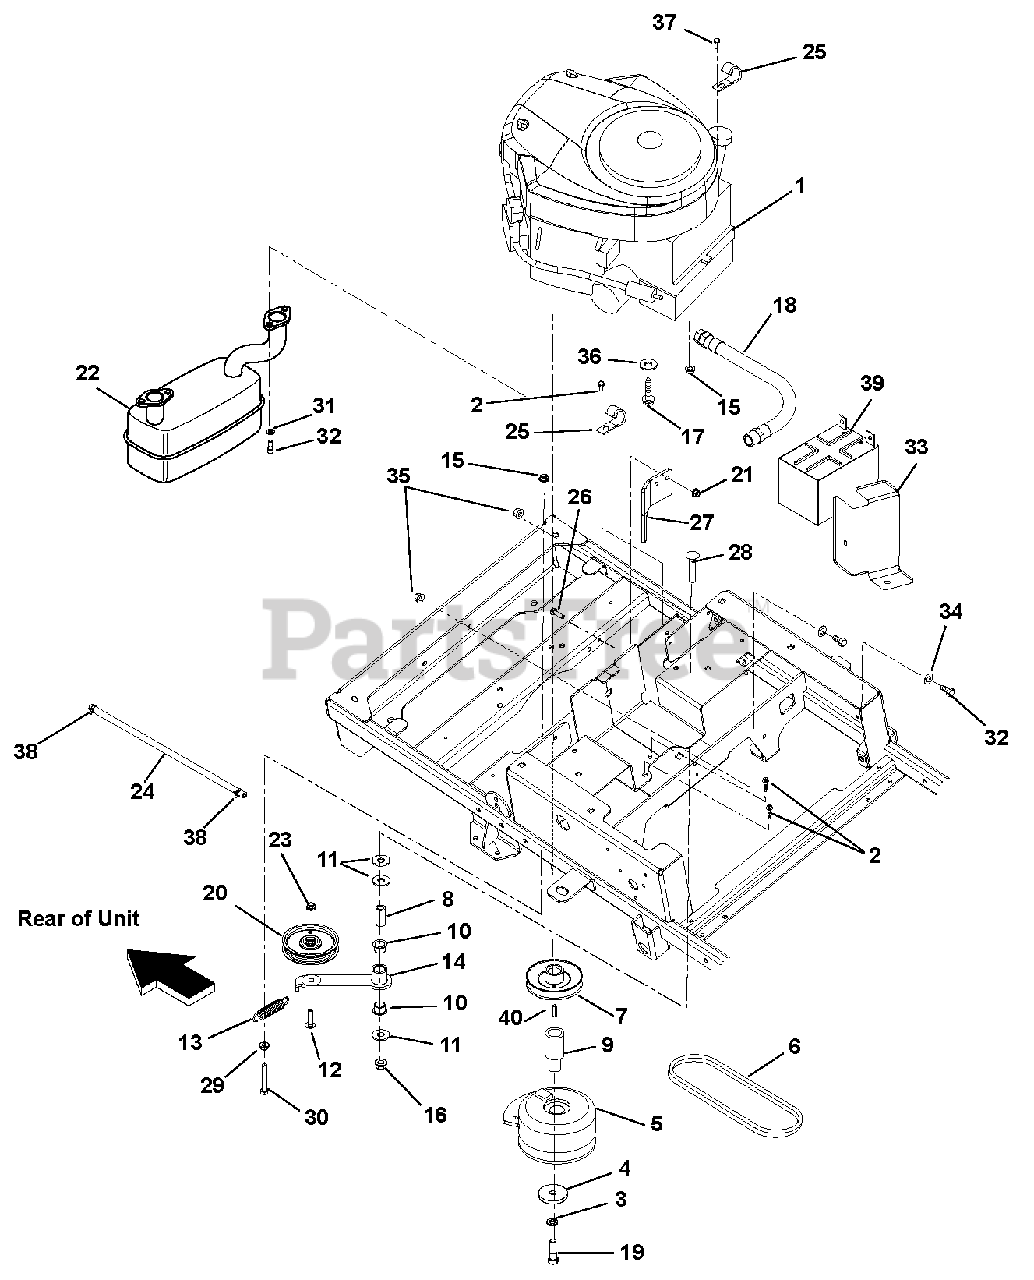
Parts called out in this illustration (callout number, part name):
1	Engine, Kawasaki FR651V
2	Screw, Tapping .250-20 x .37 Hex Washer Head
3	Washer, Locking .44 x .109 Regular
4	Washer, Flat Steel .469 x 2.00 x .25
5	Clutch, XL 6.83"
6	Belt, HA 62.50 Wrapped
7	Pulley, V 4.5 x 1.00 AB Section with Key
8	Bushing, Sleeve .500 x .750 x 1.560
9	External, Crankshaft Lower
10	Bushing, Flange 0.75 x 0.875 x .625 x 1.125
11	Washer, Flat Steel .563 x 1.38 x .109
12	Bolt, Round Head Square Neck .38-16 x 1.50 Grade 5
13	Spring, Tension .105 x .812 x 3.88
14	Weldment, Ground Drive Idler Arm
15	Nut, 3/8-16 Flange Nyloc
16	Nut, Locking Top Flange .50-13
17	Bolt, Hex .38-16 x 1.25
18	Hose Assembly, Oil Drain
19	Bolt, Hex .44-20 x 4.50 Grade 8
20	Assembly, 4" Idler
21	Nut, .31-18 Nyloc Flange
22	Muffler, Kawasaki Twin Courage
23	Nut, Locking Top Flange .38-16
24	Fuel Hose
26	Bolt, Hex .31-18 x 1.00 Grade 5
27	Clutch Stop
28	Bolt, Round Head Square Neck .50-13 x 2.50 Grade 5
29	Nut, Flange .375-16
30	Bolt, Hex .38-16 x 2.50 Grade 5
31	Washer, Locking .31 x .078 Regular
32	Bolt, Hex .25-20 x .75
33	Bracket, Battery Holder
34	Washer, Flat Steel .281 x .62 x .065
35	Nut, KEPS .250-20
36	Washer, Flat Steel .406 x .812 x .065
37	Bolt, Hex .38-16 x .75 Grade 5
38	Clamp, Fuel Line
39	Battery, 12V, 215 CCA, GEP
40	Key, Straight .25 x 2.0 x .25
